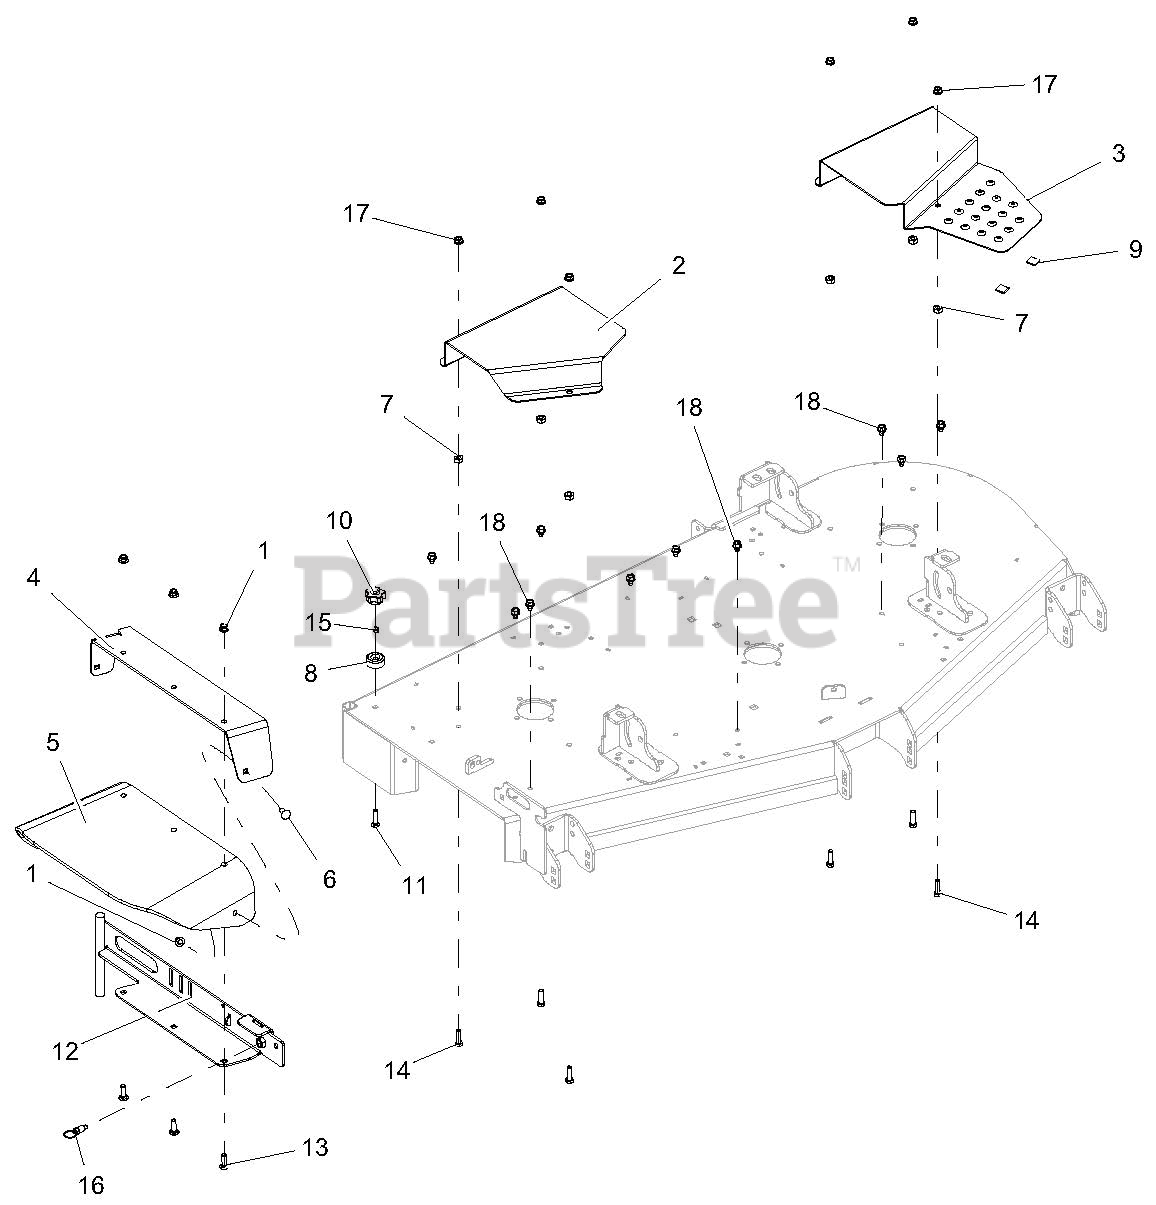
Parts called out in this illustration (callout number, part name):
1	NUT-LK-NYL-FLG .38-16 YWZC
2	GUARD, 60"-66" RH DECK BELT-RED
3	GUARD, 60" LH DECK BELT-W/STEP-RED
4	DISCHARGE CHUTE SUPPORT W/SAFETY DECAL-RED
5	CHUTE, RUBBER DISCHARGE
6	BLT-RDHDSQNK .38-16X1.00 G5 YWZC
7	NUT-HEAVY HEX .38-16 YWZC
8	BUMPER, RECESSED 1.50 X .63 W/.31 HOLE
10	KNOB, CLAMPING
11	BLT-RDHDSQNK .31-18X1.50 G5 YWZC
12	WLDMT, 52"-60" DISCH CHUTE MTG-RED
13	BLT-RDHDSQNK .38-16X1.25 G5 YWZC
14	BLT-HEX .38-16X1.25 GR5 YWZC
15	NUT-LK-CTR .31-18 YWZC
16	PULL PIN,.50-13THDX.310 PLNGR
17	@NUT-SPNLK-FLG .375-16 YWZC
18	SCR-TAP .38-16X.50 HWH TR YWZ
